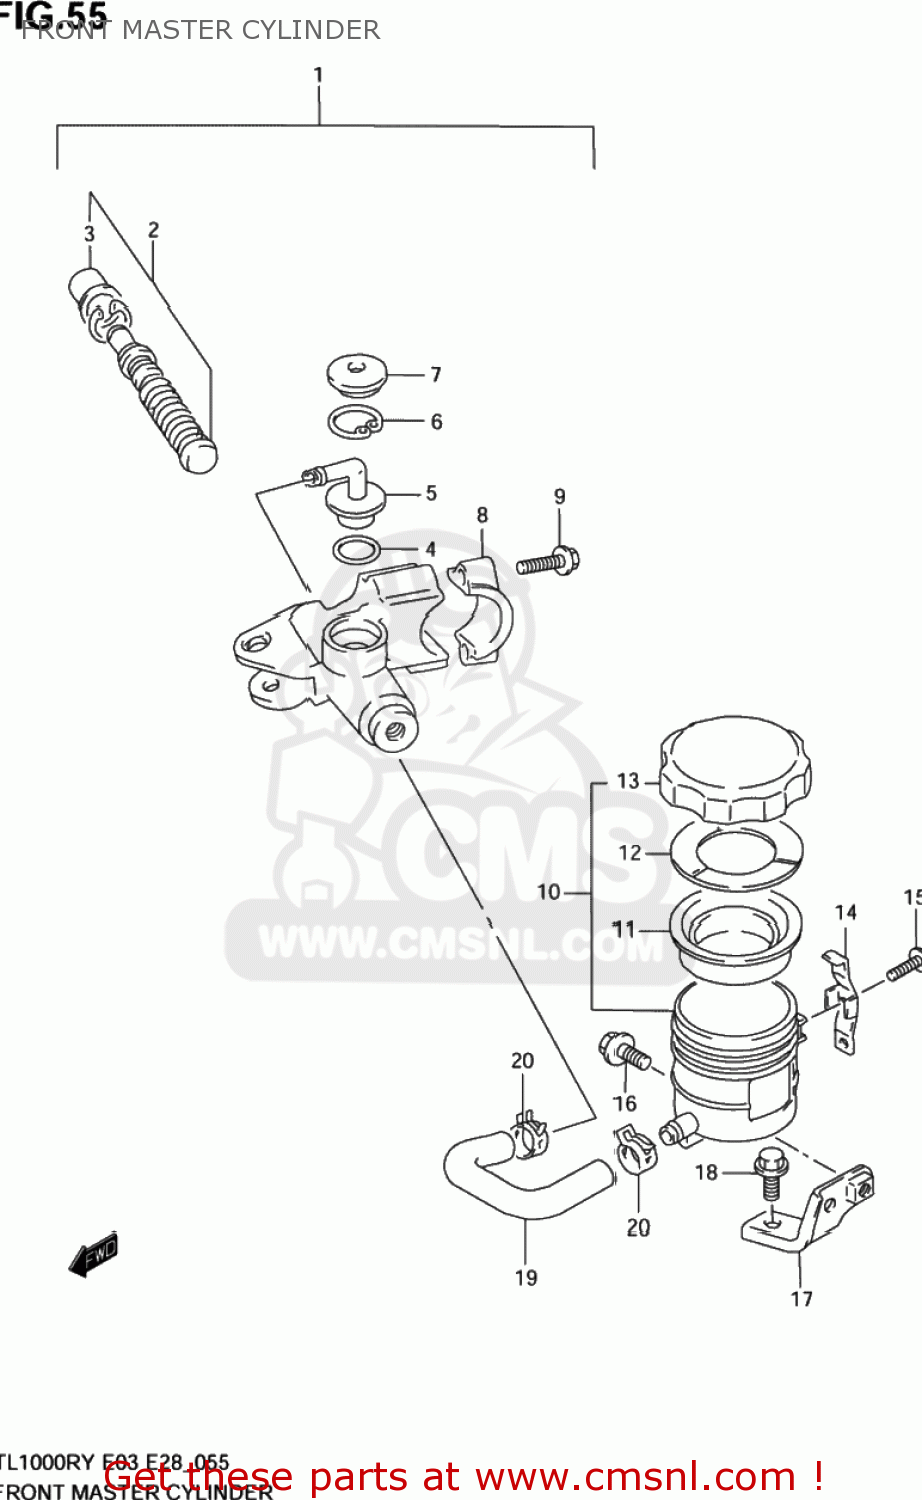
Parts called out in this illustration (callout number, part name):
1	CYLINDER ASSY,FR MASTER
2	PISTON & CUP SET
3	BOOT
4	O RING
5	CONNECTOR
6	CIRCLIP
7	COVER,DUST
8	HOLDER
9	BOLT(6X25)
10	TANK ASSY,RESERVOIR
11	DIAPHRAGM
12	PLATE,DIAPHRAGM
13	CAP
14	PLATE,RESERVOIR TANK CAP
15	SCREW
16	BOLT
17	BRACKET,RESERVOIR TANK
18	BOLT
19	HOSE,RESERVOIR TANK FR
20	CLAMP,RESERVOIR TANK FR
